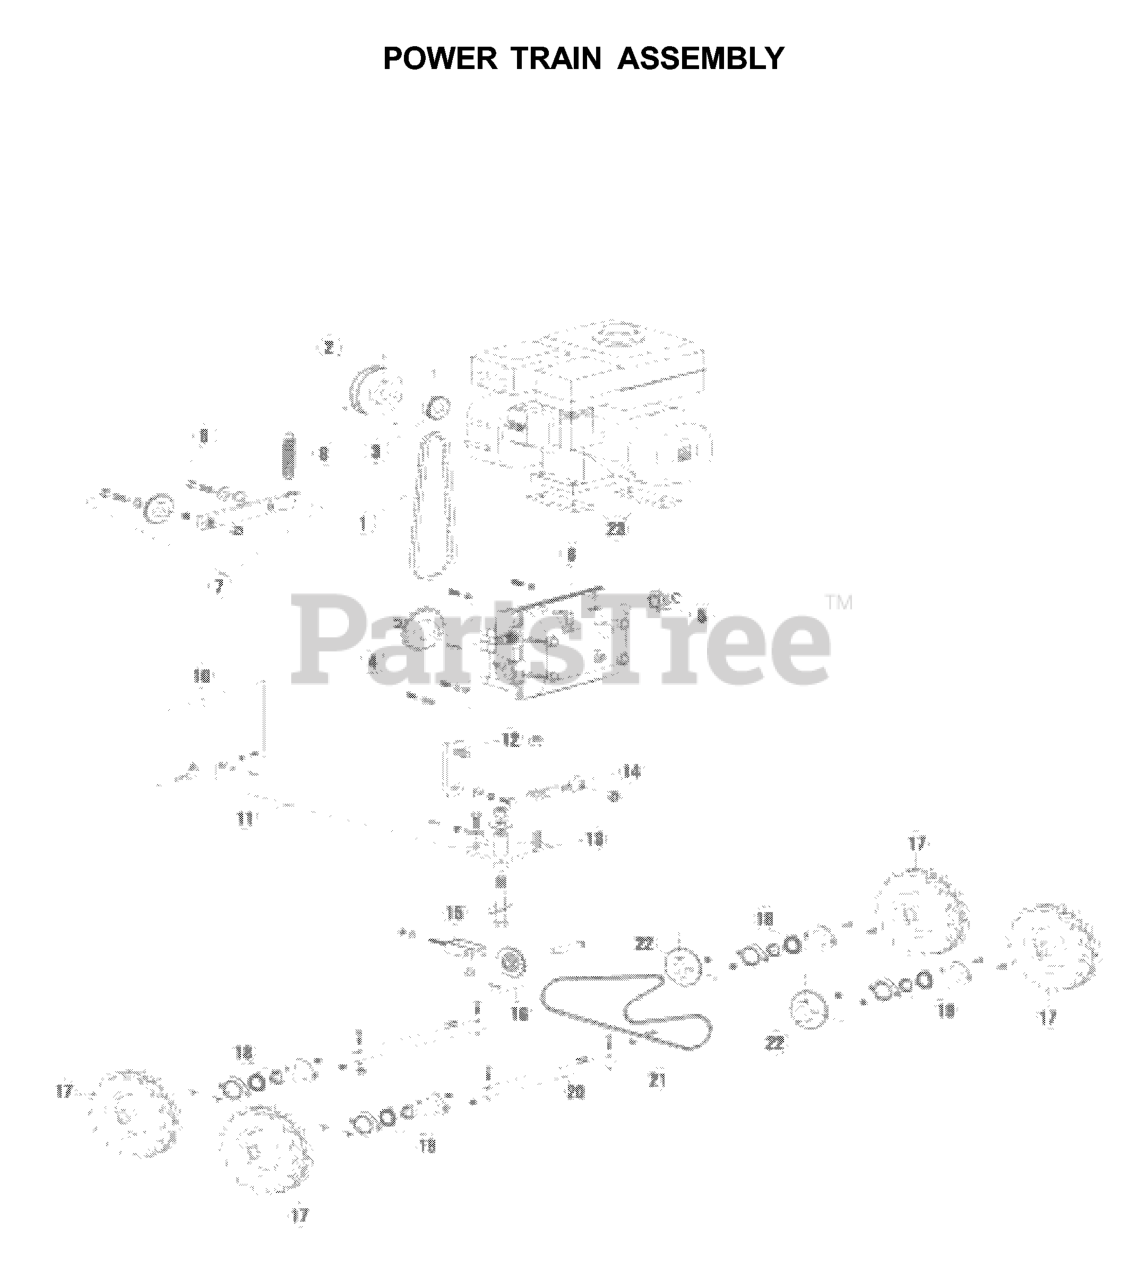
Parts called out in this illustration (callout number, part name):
1	CHAIN, TRANSMISSION
2	V-PULLEY
3	SPROCKET
4	SPROCKET, W/KEY AND RING
5	SPROCKET, TRANSMISSION
6	TRANSMISSION W/HARDWARE
7	CHAIN, IDLER ARM ASSY
8	SPRING, IDLER CAM, 3 3/4"
9	SPROCKET
10	LEVER ORANGE,SHIFT KIT
11	LINKAGE, SHIFT
12	ARM
13	BELL CRANK SHIFT KIT
14	ROD END
15	TENSIONER ASSY
16	SPROCKET
17	WHEEL-10" WITH HARDWARE
18	BEARING 1"
19	STAMPING KIT
20	AXLE, WHEEL, W/PINS
21	CHAIN,55" DRIVE
22	SPROCKET
23	MOTOR SPACE PLATE KIT
